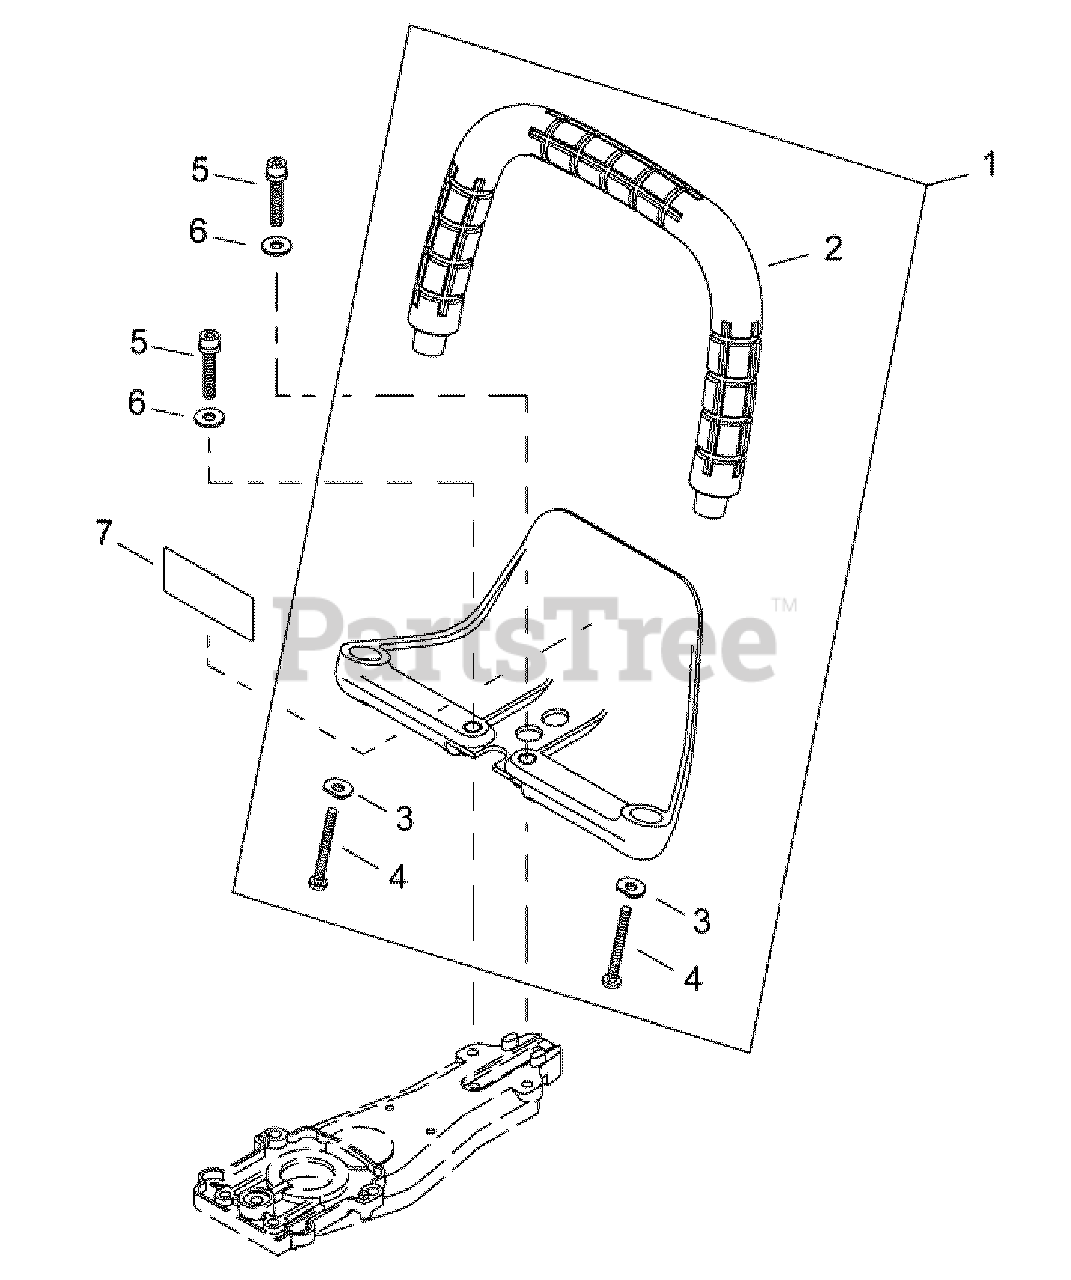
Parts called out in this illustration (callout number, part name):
1	HANDLE ASSY, FRONT
2	HANDLE, FRONT
3	WASHER
4	BOLT, TAPPING 5
5	BOLT M6×30
6	WASHER Ø16ר6.5×1.6 MM
7	LABEL, CAUTION
